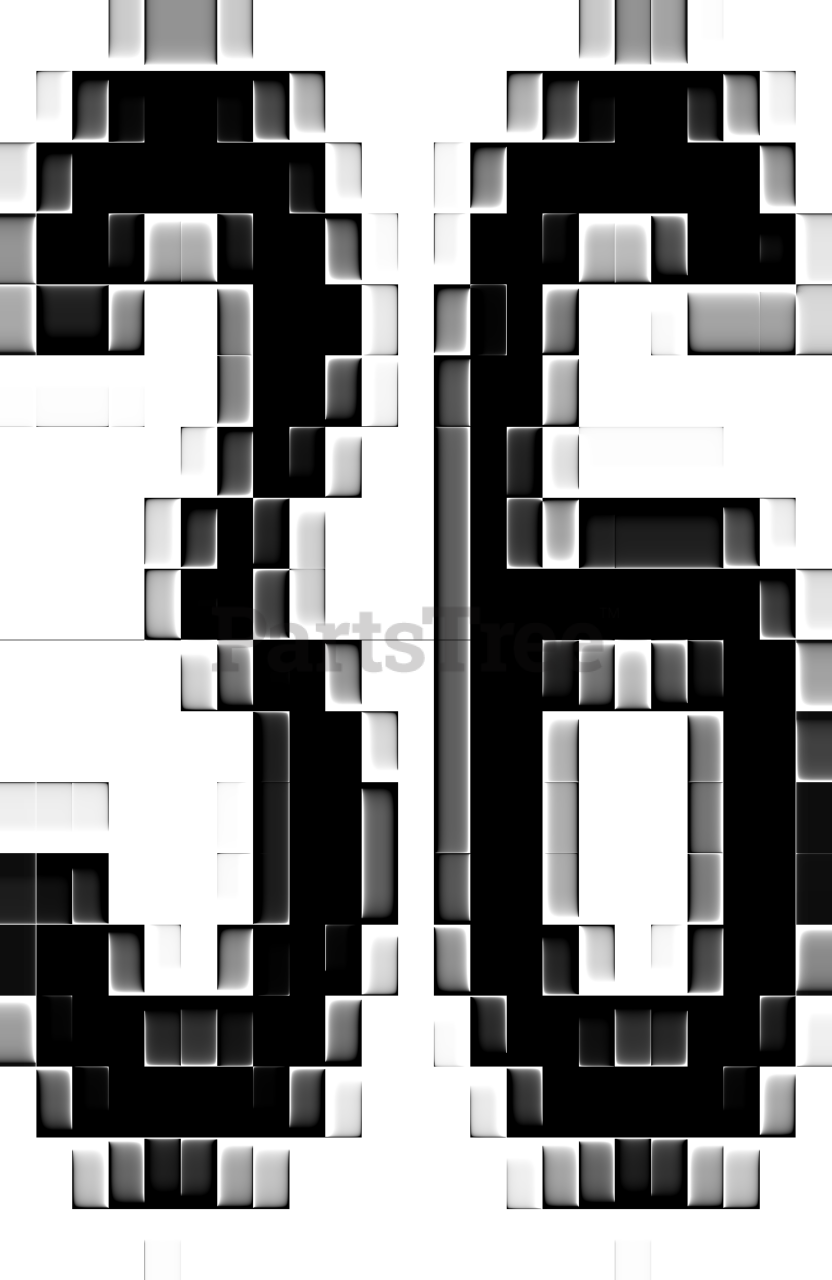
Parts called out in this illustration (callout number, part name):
8	SCREW EHHFM
11	SCREW M6S 5X20
13	LOCKNUT M5
17	COVER FUSE HOLDER
33	THROTTLE HANDLE ASSY
87	LOCKNUT M8
